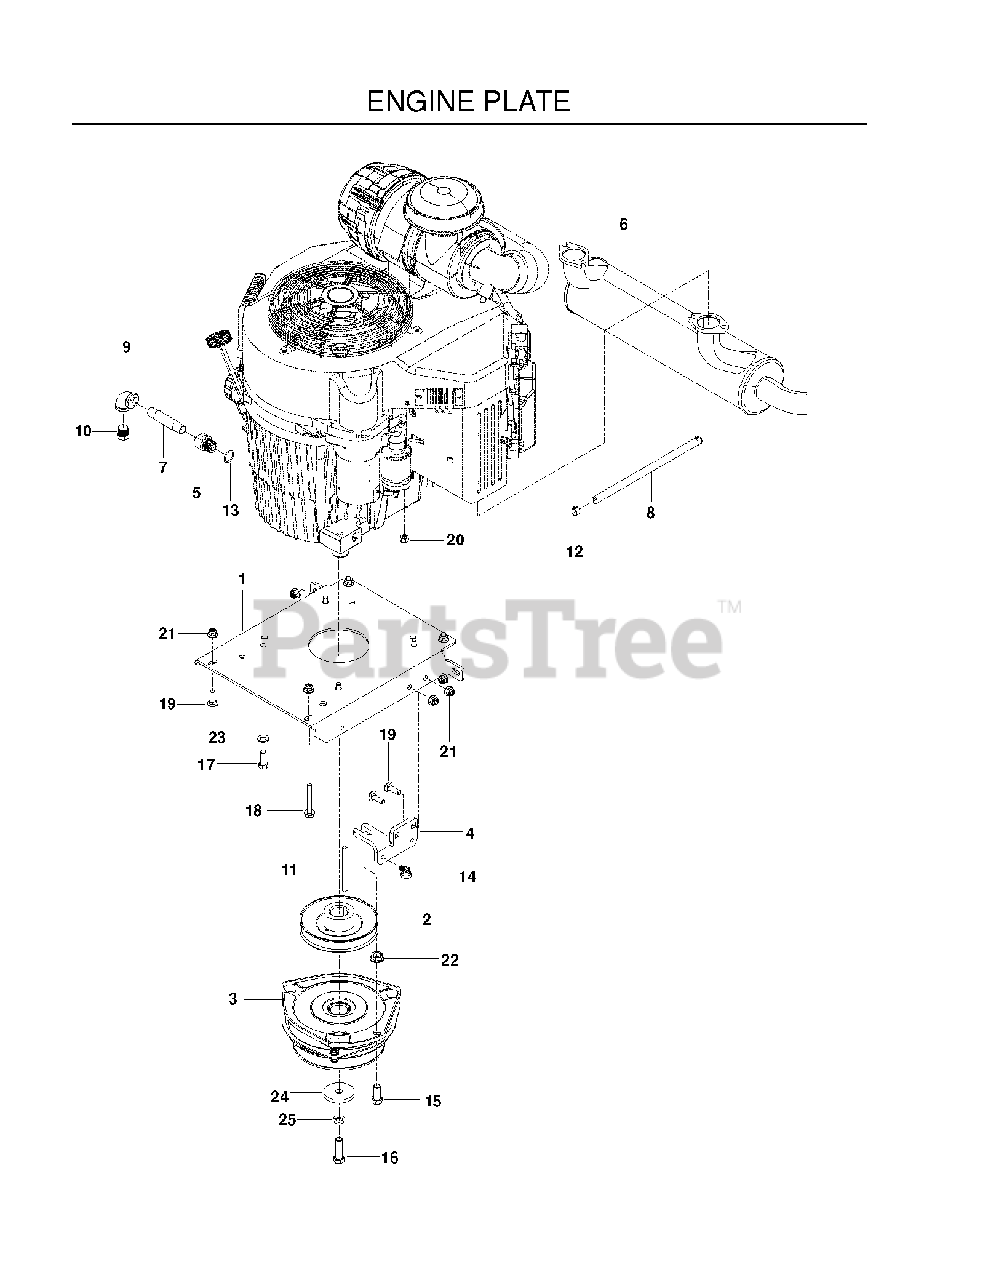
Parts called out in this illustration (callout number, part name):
1	PLATE, ENGINE, BLACK
2	PULLEY, ENGINE
3	CLUTCH, GT3.5
4	STOP, CLUTCH, OGURA
5	ADAPTER, OIL DRAIN
6	MUFFLER, 29HP KAW FX751V-850V
8	FUEL LINE (5")
9	90 DEG.ELBOW 3/8NPT
10	PLUG, DRAIN 3/8 NPTF
11	KEY, 1/4 SQ X 3.5
12	HOSE CLAMP
14	TIE WRAP, 8-3/8", W/CLIP
15	HCS 7/16-14 X 1 GR 5 ZD
16	HCS 7/16F X 1 1/2
17	HCS 3/8C X 1
18	HHFS 5/16-18 X 2.25 GD 5
19	RHSNB 5/16C X 1
20	NUT M8-1.25 TOP NYL GR10 ZD
21	5/16-18 NYLOC FLANGE NUT
22	NUT 7/16C WHIZ
23	WASHER, 3/8 DISC SPRING SPEC
24	BLADE WASHER
25	WASHER 7/16 LOCK
